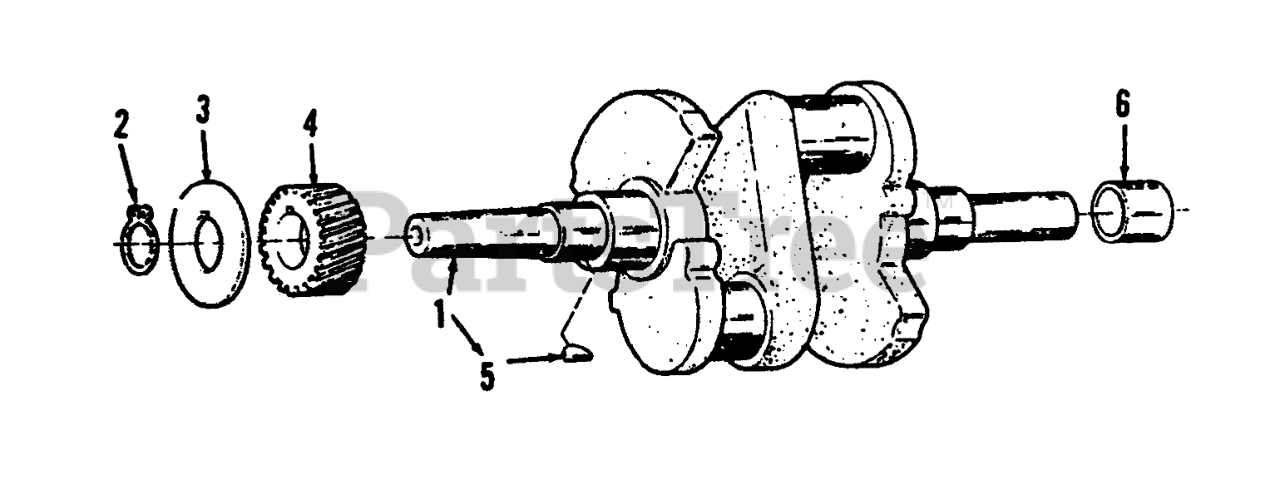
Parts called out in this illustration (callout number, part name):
1	CRANKSHAFT
2	Retaining Ring
3	Washer
4	Gear
5	Key
6	Cover-Valve
